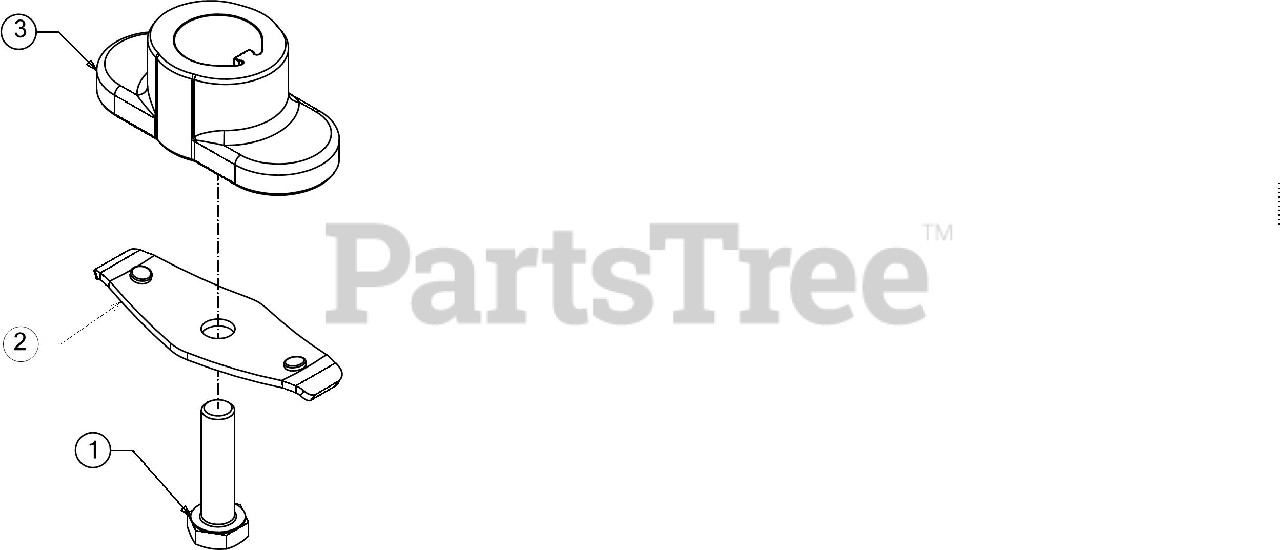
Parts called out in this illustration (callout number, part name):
1	SCREW 3/8-24 X 1.50 GR8
2	BLADE BELL SUPPORT
3	BLADE ADAPTER 25MM X 1.19
